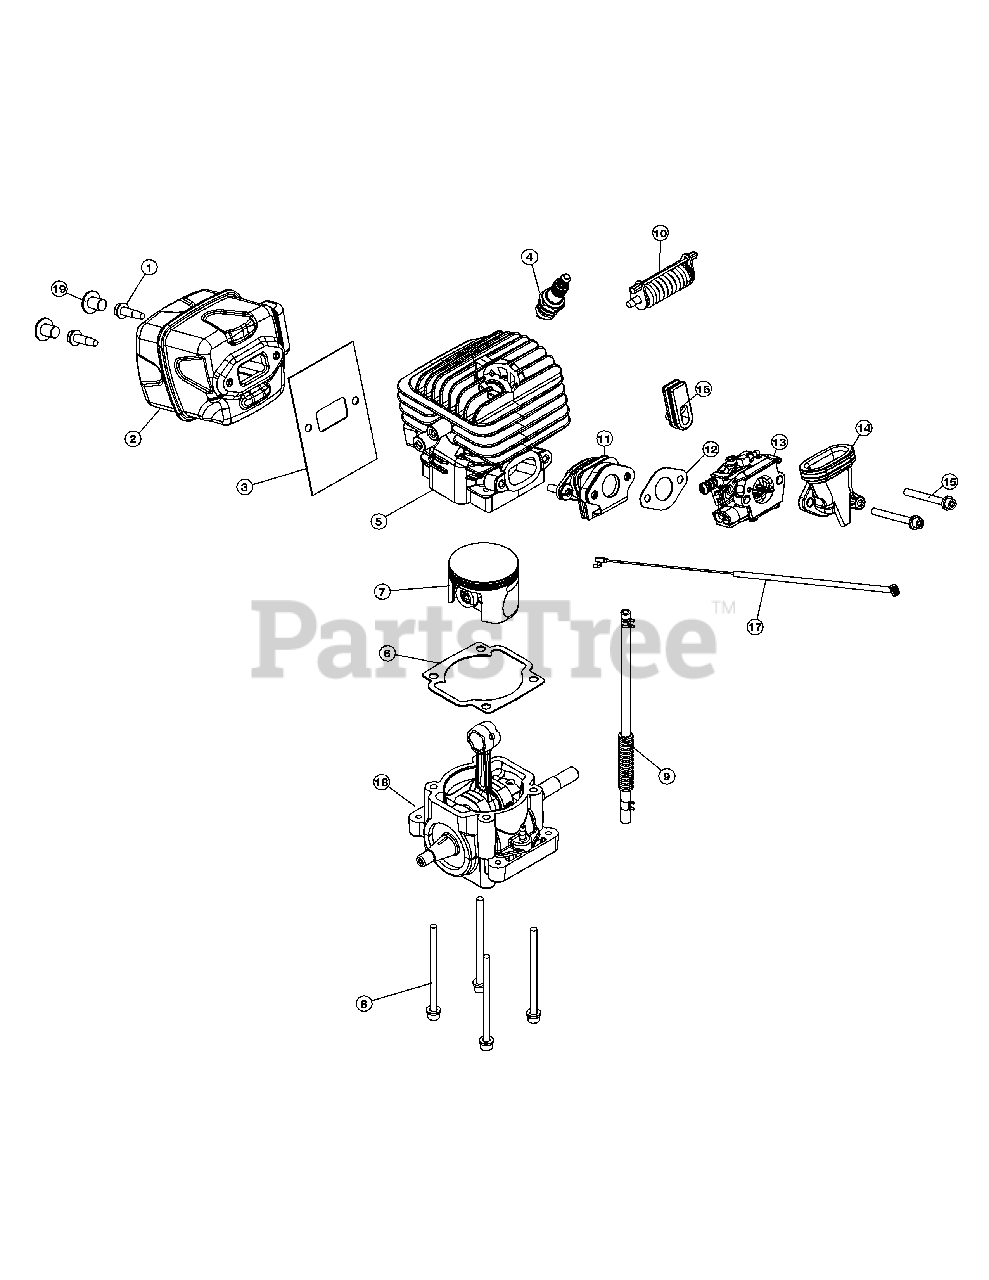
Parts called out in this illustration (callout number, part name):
1	Muffler Screw
2	Muffler Assembly (Incl. 1, 3 & 19)
3	Muffler Gasket
4	Spark Plug
5	Cylinder Assembly
6	Cylinder Gasket
7	Piston Assembly
8	Carburetor Hardware Kit (4 screws)
9	Breather Hose w/clamp
10	Isolator Assembly
11	Insulator Assembly
12	Carburetor Gasket
13	Carburetor
14	Boot, Bracket & Cable Assembly (Incl. 16 & 17)
15	Carburetor Hardware Kit (2 screws)
16	Grommet
17	Throttle Cable
18	Shortblock Assembly (Incl. 4-10)
19	Muffler Plug
